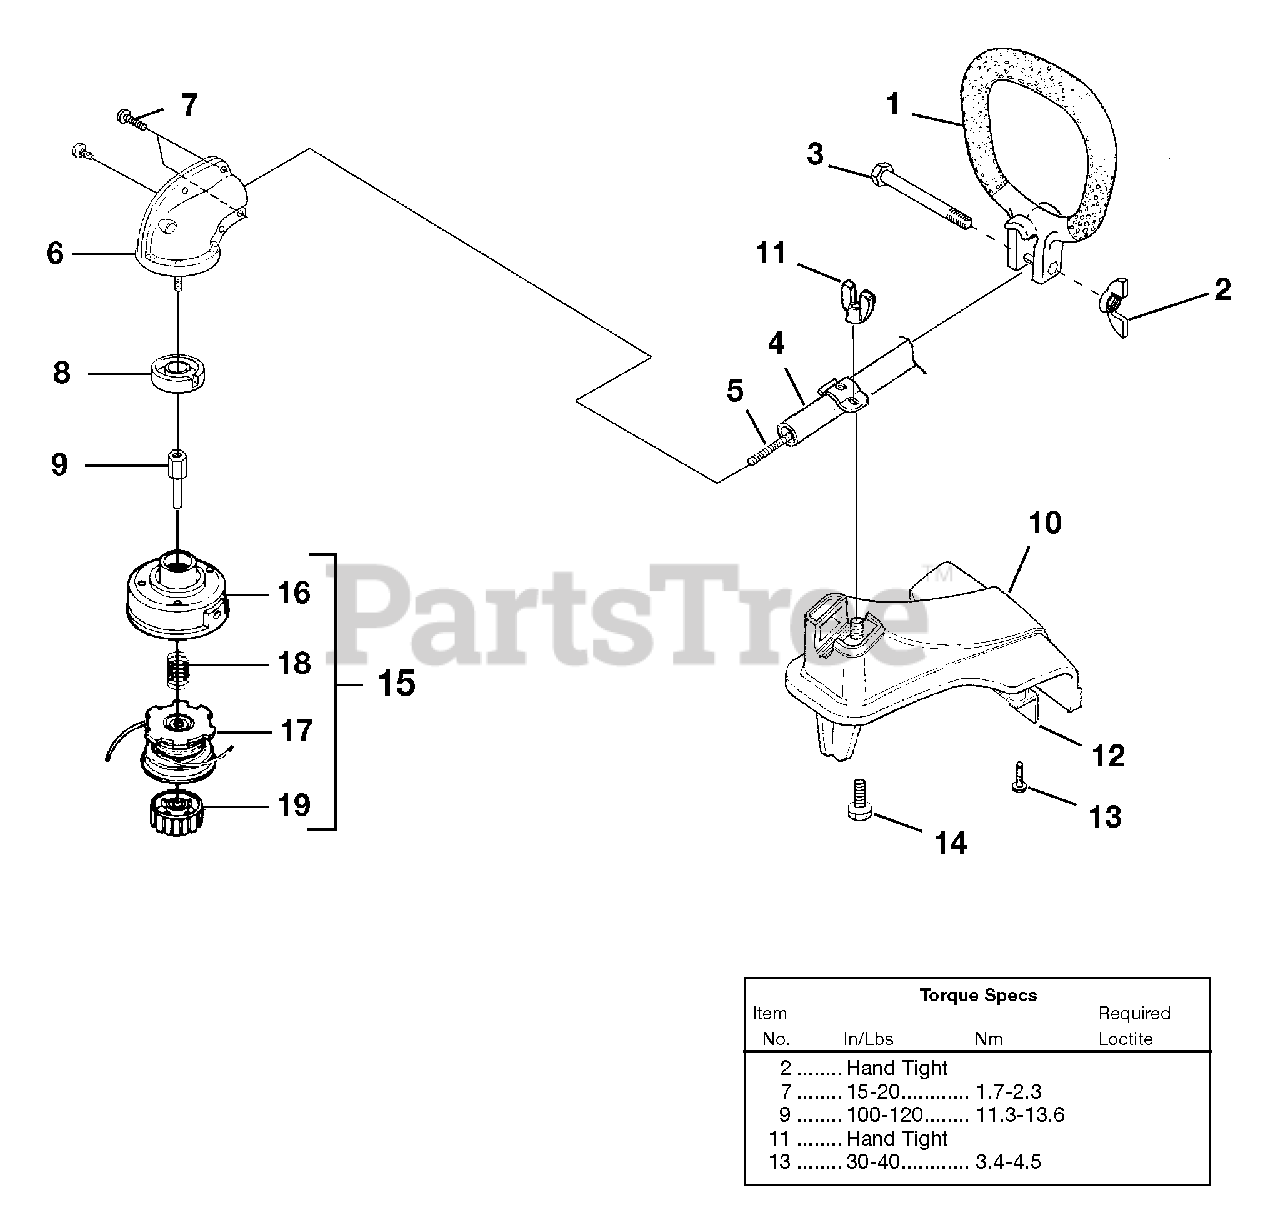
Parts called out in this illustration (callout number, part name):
1	HANDLE-FRONT
2	NUT-Wing, Washer Faced (1/4-20)
3	SCREW-Cap Hex Hd. (1/4-20 x 2")
4	DRIVESHAFT HOUSING ASSY.
5	SHAFT-Flexible
6	GEARHEAD ASSY.
7	Screw, Taptite Hex Hd. (10-24 x 1/2")
8	WASHER-Flanged
9	ADAPTER-Shaft
10	GRASS DEFLECTOR KIT
11	WING NUT
12	BLADE-Cut-off
13	SCREW-Mach.Hex Hd. (10-24 X 3/8")
14	SCREW-Square Head
15	STRINGHEAD-Complete (.080" Line)
16	HOUSING & EYELET (Dual Line)
17	SPOOL & STRING (.080" Line)
18	SPRING-Compression
19	RETAINER-Spool (RH Thread, Black)
